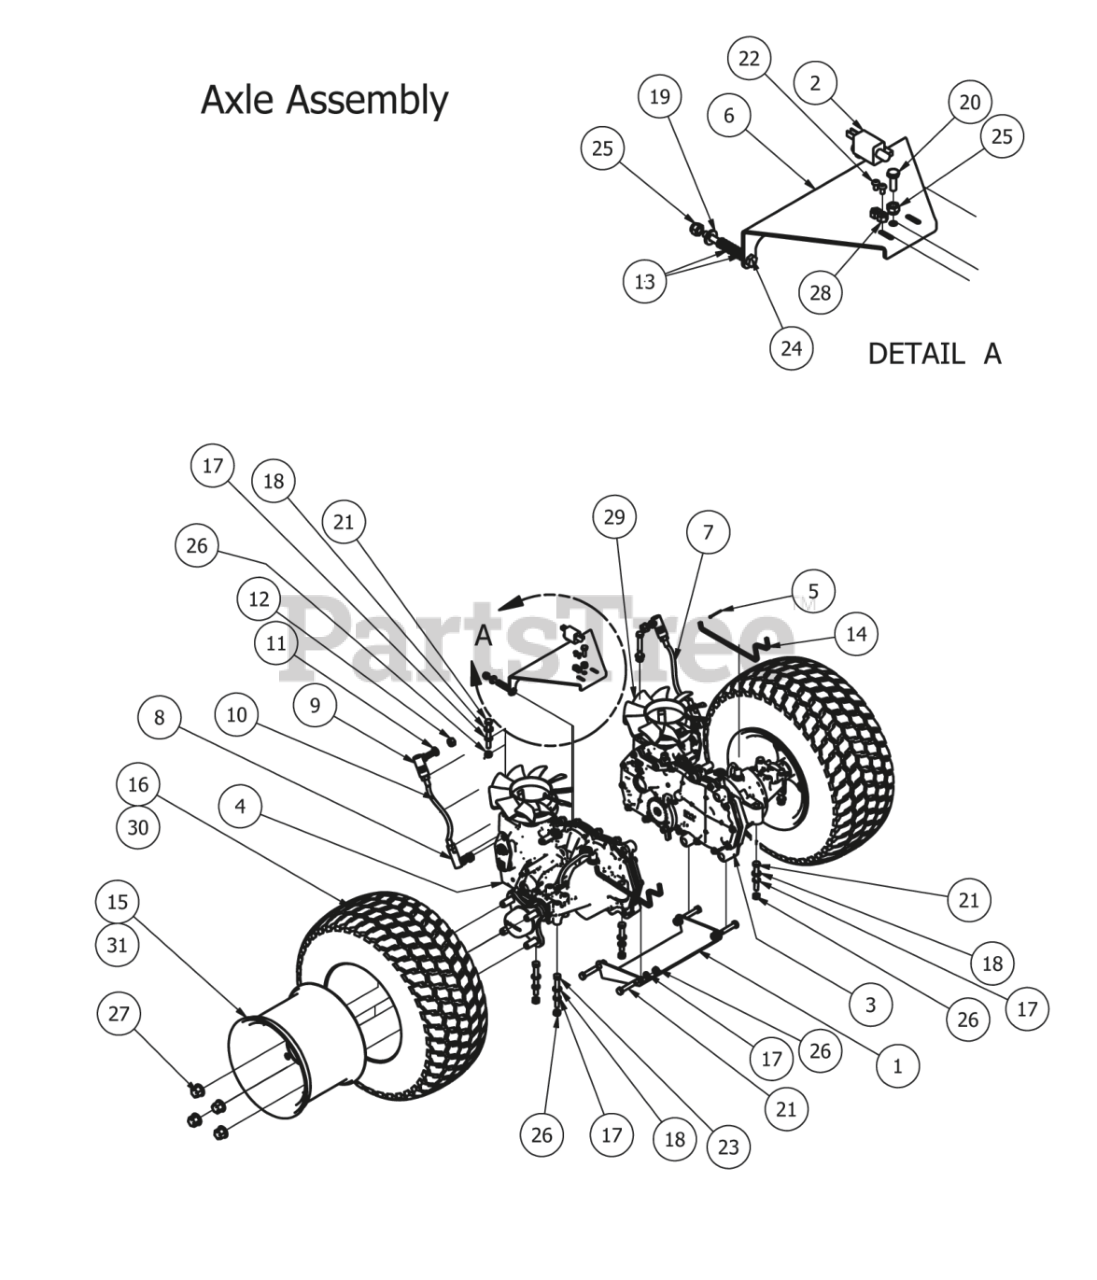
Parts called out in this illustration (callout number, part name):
1	MZ Transaxle Support (Lower)
2	Safety Switch
3	EZT Left MZ Models
4	EZT- Right MZ Models
5	Cotter Pin-Brake bar on Mz
6	MZ Brake Lock Bracket
7	Steering linkage for Mz Left
8	3/8-24 Ball Joint
9	Quick Release Ball Joint
10	Steering linkage for Mz right
11	3/8" Lock Washer
12	3/8" Fine Threaded Jam Nut
13	Brake Spring
14	MZ Brake Release Bar
15	Rear rim for a 48in
16	18 x 9.50 -8 Tire Only MZ 48" Deck only
17	5/16" Lock Washer
18	5/16" Flat Washer
19	1/4" Flat Washer
20	1/4" x 3/4" Hex Bolt
21	5/16" x 2 1/2" Bolt
22	10-24 X 5/8 BS C/S 18-8 SS
23	5/16" x 3" Hex Bolt
24	1/4-20 x2-1/2 Gr2 hex C/s zinc
25	1/4" Nylock Nut
27	Acorn Lug Nut
28	10-24 Nylon Insert Locknut
29	MZ Fan & Pulley Kit
30	42" MZ 18x 7.50-8 tire only
31	Rear rim only 42" MZ
